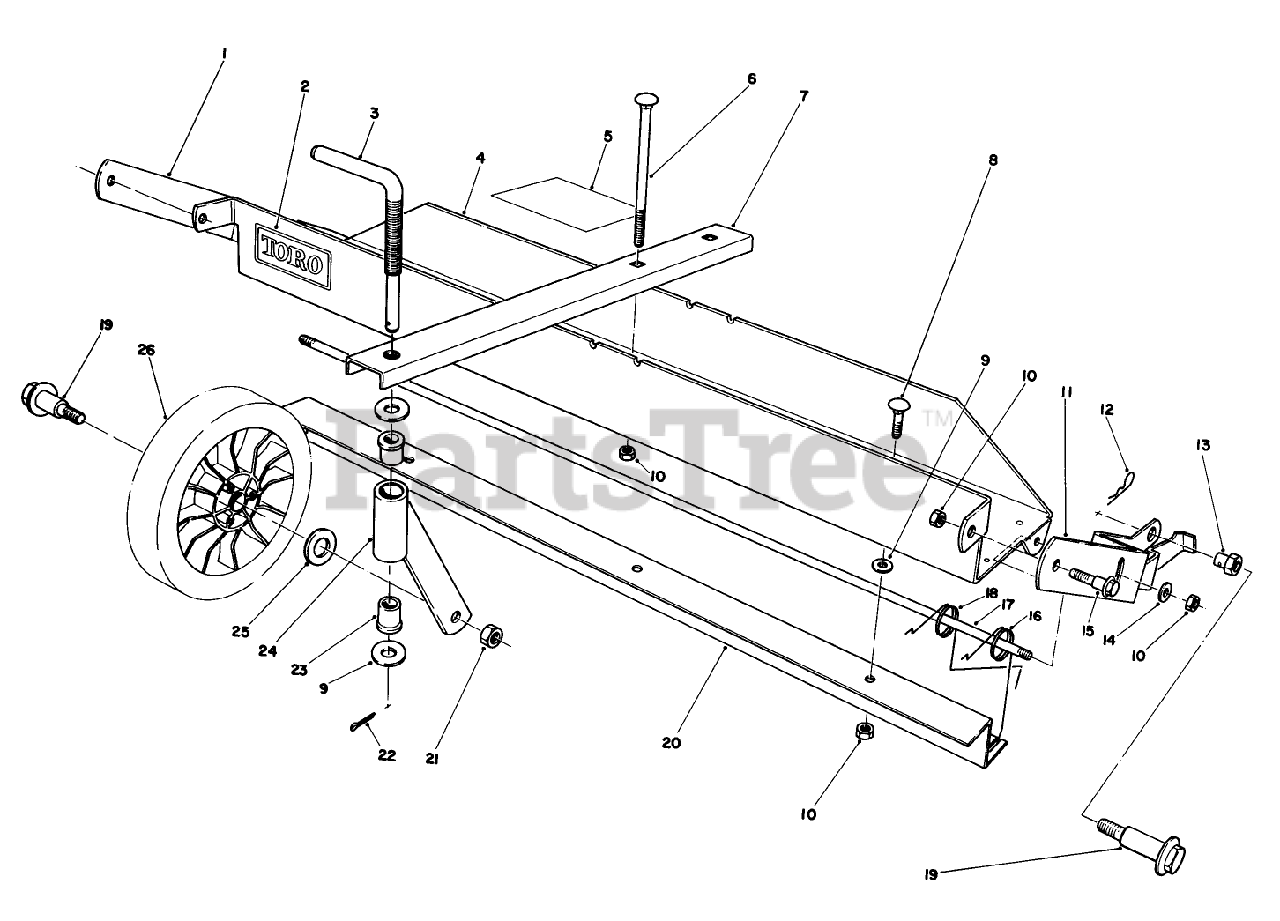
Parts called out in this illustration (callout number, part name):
3	CASTOR ADJ ROD
6	SCREW-CARR
8	BOLT-CARR
9	WASHER-PLAIN
10	NUT-HEX, SIDE DEFORM
12	PIN-COTTER, HAIR
13	PIVOT NUT
14	WASHER-FLAT
15	BOLT-SHOULDER,HFH
18	DETHATCHER SPRING
19	BOLT-WHEEL
20	SPRING GUIDE STRAP
21	NUT-LOCK
22	PIN-COTTER
25	WASHER
